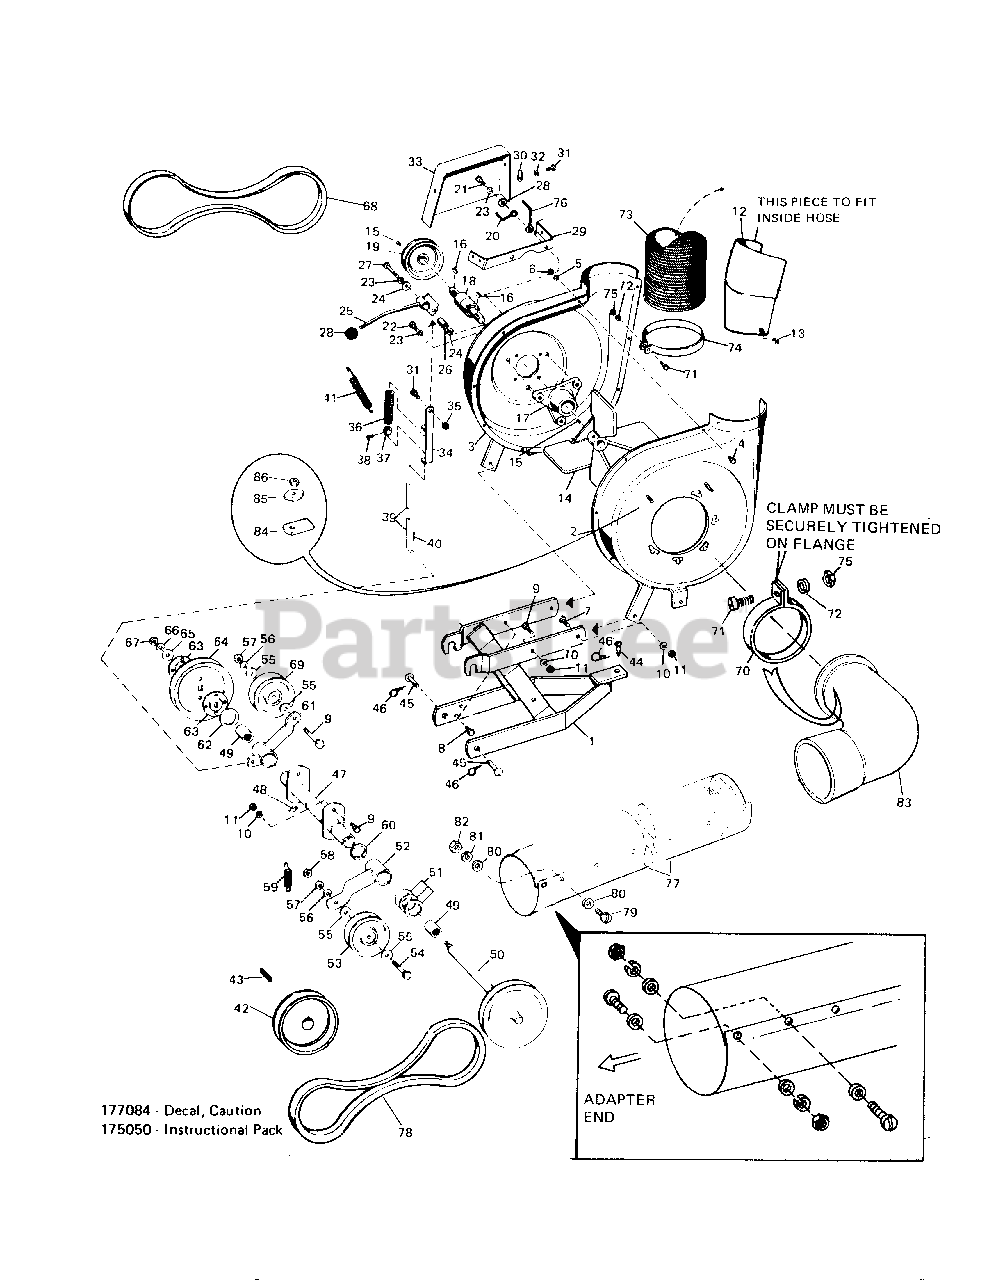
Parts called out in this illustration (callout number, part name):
1	Blower Housing Support Assy.
2	Housing Assy. Inlet Half
3	Housing Assy. R.H. Half
4	Hex Capscrew, 1/4-20 x 1/2
5	Lockwasher, 1/4
6	Hex Nut Full, 1/4-20
7	Hex Capscrew, 3/8-16 x 1
8	Hex Capscrew, 3/8-16 x 1-1/4
9	Hex Capscrew, 3/8-16 x 1-1/2
10	Lockwasher, 3/8
11	Hex Nut Full, 3/8-16
12	Deflector
13	Self-Tapping Screw, No. 10 x 3/8
14	Fan Assembly
15	Set Screw Sq. Hd. 5/16-18 x 1/2
16	Key Hi-Pro
17	Flange, Shaft & Bearing Assy.
18	Shaft and Bearing
21	Hex Capscrew, 3/8-16 x 1
22	Hex Capscrew 3/8-16 x 1
23	Lockwasher, 3/8
24	Plain Washer
25	Clutch Lever Assembly
26	Spacer, Clutch Lever
27	Hex Capscrew, 3/8-16 x 2
29	Bracket, Belt Guard
30	Nut Retainer
31	Hex Capscrew, 5/16-18 x 5/8
32	Lockwasher, 5/16
33	Belt Guard
34	Rod Guide Assembly
35	Hex Nut Full, 5/16-18
38	Set Screw Sq. Hd. 1/4-20 x 3/8
39	Clutch Rod-Blower
40	Cotter Pin, 3/32 x 3/4
44	Pin
46	Spring Clip
47	Bearing Housing Assy.
48	Grease Fitting
49	Needle Bearing
50	Tranverse Shaft Assy.
52	Tension Arm Assembly
53	Idler Pulley
54	Hex Capscrew, 3/8-16 x 2
55	Plain Washer, 3/8
56	Lockwasher, 3/8
57	Hex Nut Full, 3/8-16
58	Hex Nut Full Lock, 3/8-16
59	Spring, Tension
60	Retaining Ring
61	Idler Arm Assembly
63	Special Washer
65	Plain Washer
66	Lockwasher
67	Hex Nut Full, 7/16-14
68	"V" Belt P.T.O.
69	Pulley, Idler
70	Hose Clamp
71	Machine Screw Rd. Hd., 1/4-20 x 3
72	Lockwasher, 1/4
73	Hose Exhaust (6" Dia.)
74	Hose Clamp
75	Hex Nut Full, 1/4-20
76	Belt Stop
77	Intake Tube
78	"V" Belt
79	Truss Hd. Phillips Screw
80	Washer, 3/16
81	Lockwasher No. 10
82	Hex Nut Full, No. 10-32
83	Elbow Assembly
86	Hex Nut Full, Jam, 5/16-18
